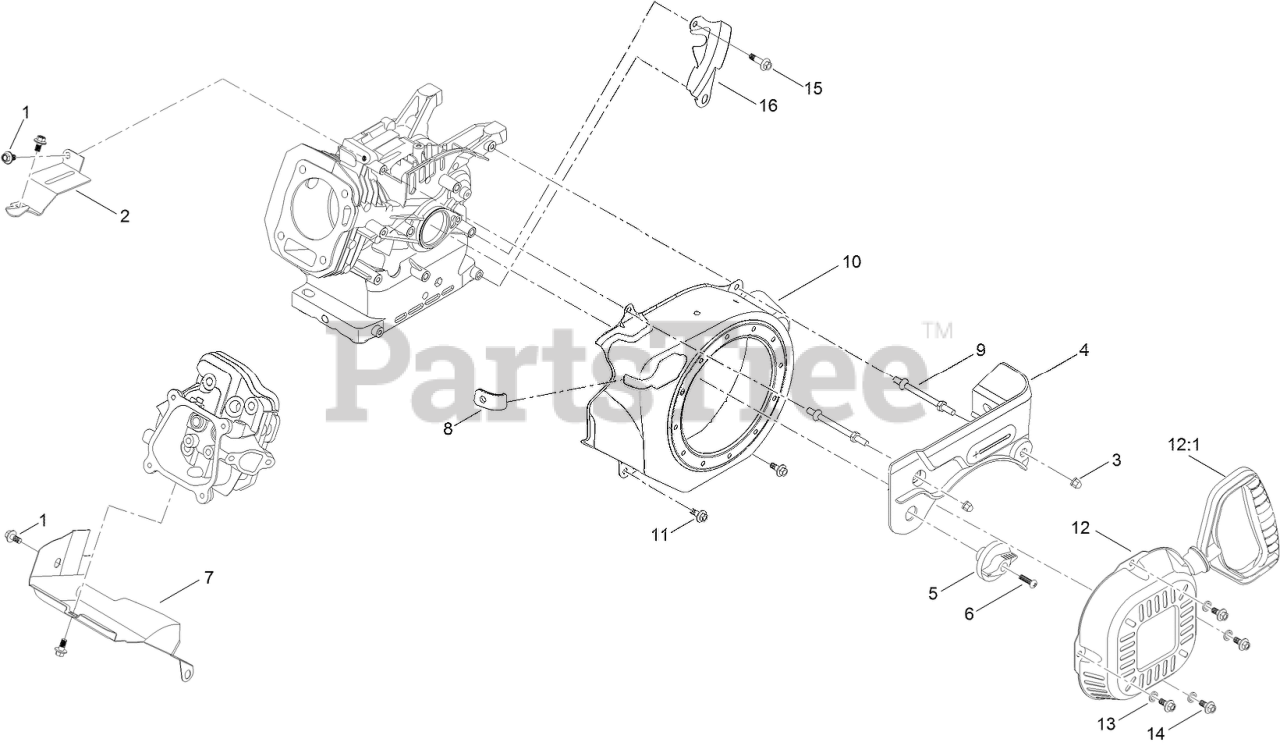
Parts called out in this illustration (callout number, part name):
1	SCREW-HHF
2	BAFFLE
3	NUT-ACORN
4	PANEL-CONTROL
5	KNOB-VALVE, FUEL
6	SCREW-BHP
7	SHROUD-LOWER
8	BLOCK-RUBBER
9	STUD-MOUNT
10	SHROUD-BLOWER
11	SCREW-HHF
12	RECOIL STARTER ASM
12:1	HANDLE-RECOIL
13	WASHER-PLAIN
14	SCREW-HHF
15	SCREW-HHF
16	SHIELD-FLYWHEEL
